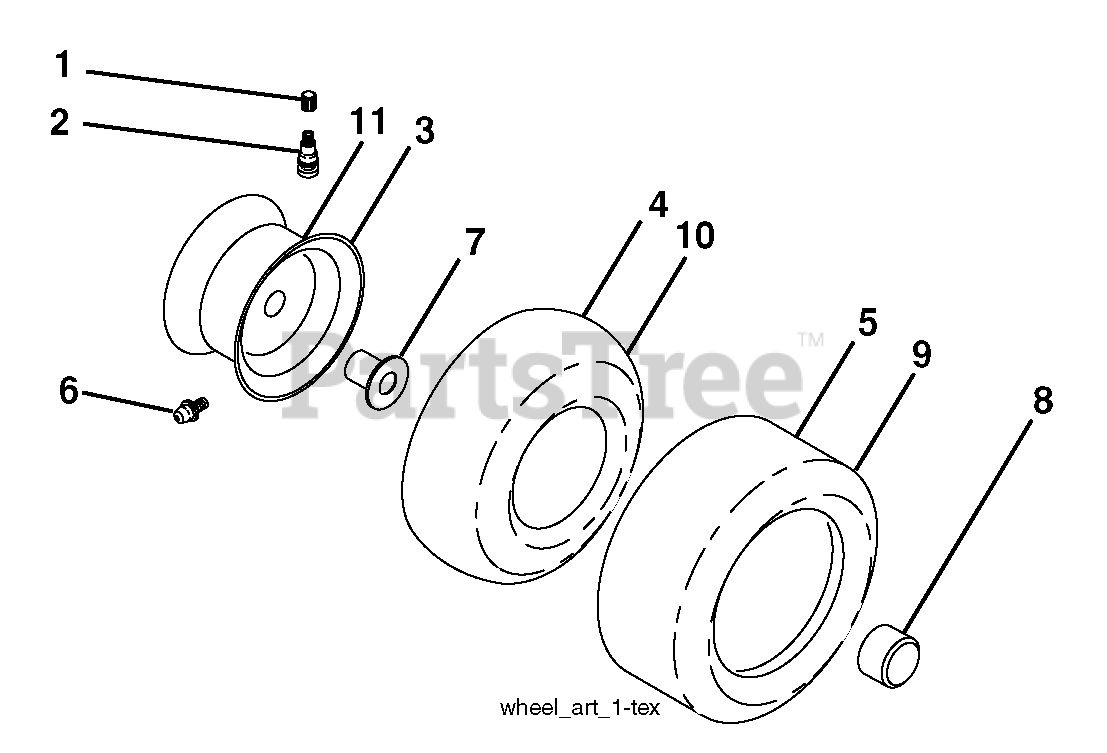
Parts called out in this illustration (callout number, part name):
1	Cap Valve Tire
2	Stem Valve
4	Tube Front
5	Tire F T
6	Fitting Grease
7	Bearing Flange
8	Cap Axle Blk 1 50 x 1 00
9	Tire R T
10	Tube Rear
11	Rim Asm 8" Rear Service
11	Sealant, Tire (10 oz. Tube)
